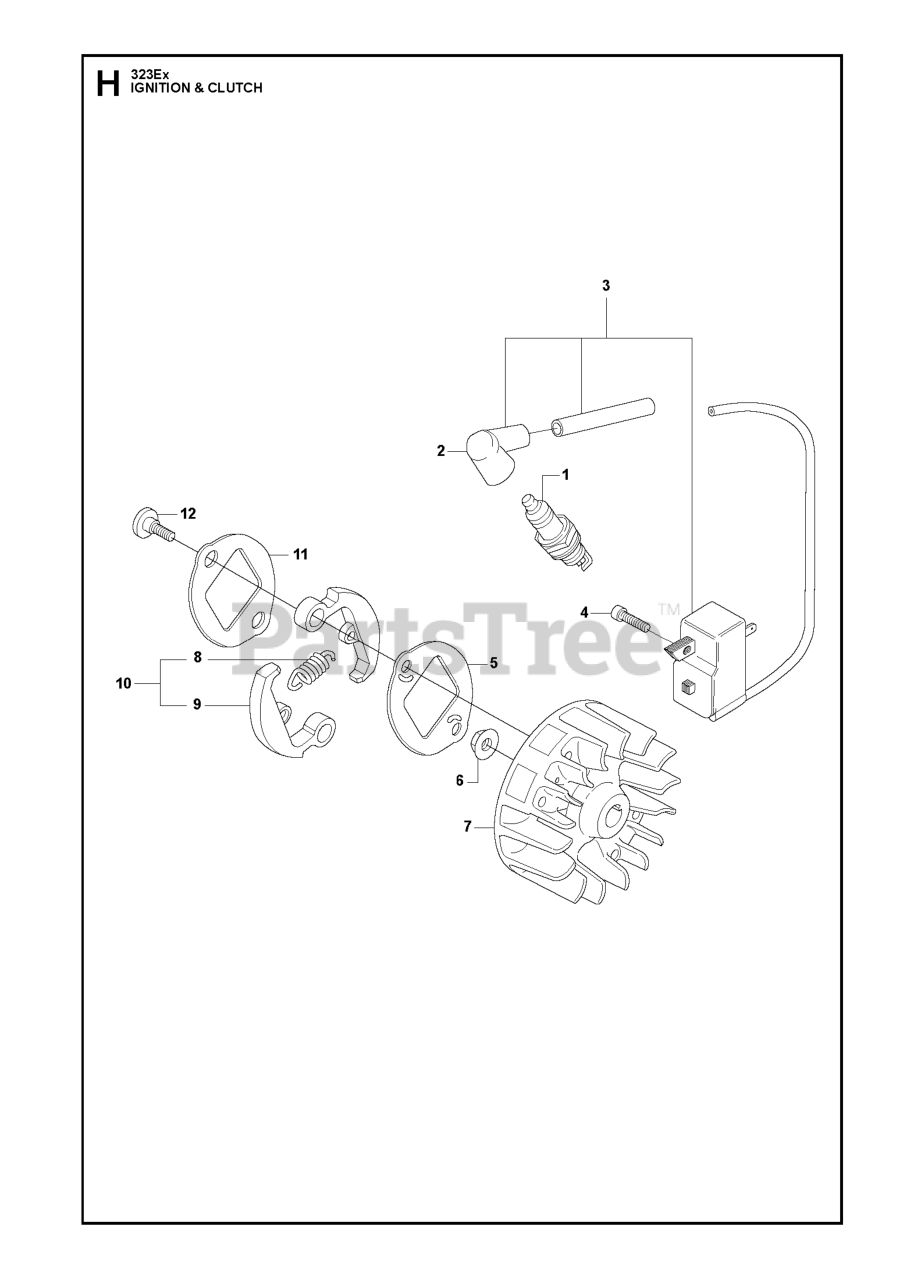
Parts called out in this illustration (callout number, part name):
1	SPARK PLUG RCJ7Y
2	SPARK PLUG CONN. KIT
3	IGNITION MODULE
4	SCREW
5	WASHER
6	FLANGE NUT
7	FLYWHEEL
11	WASHER
12	SCREW
